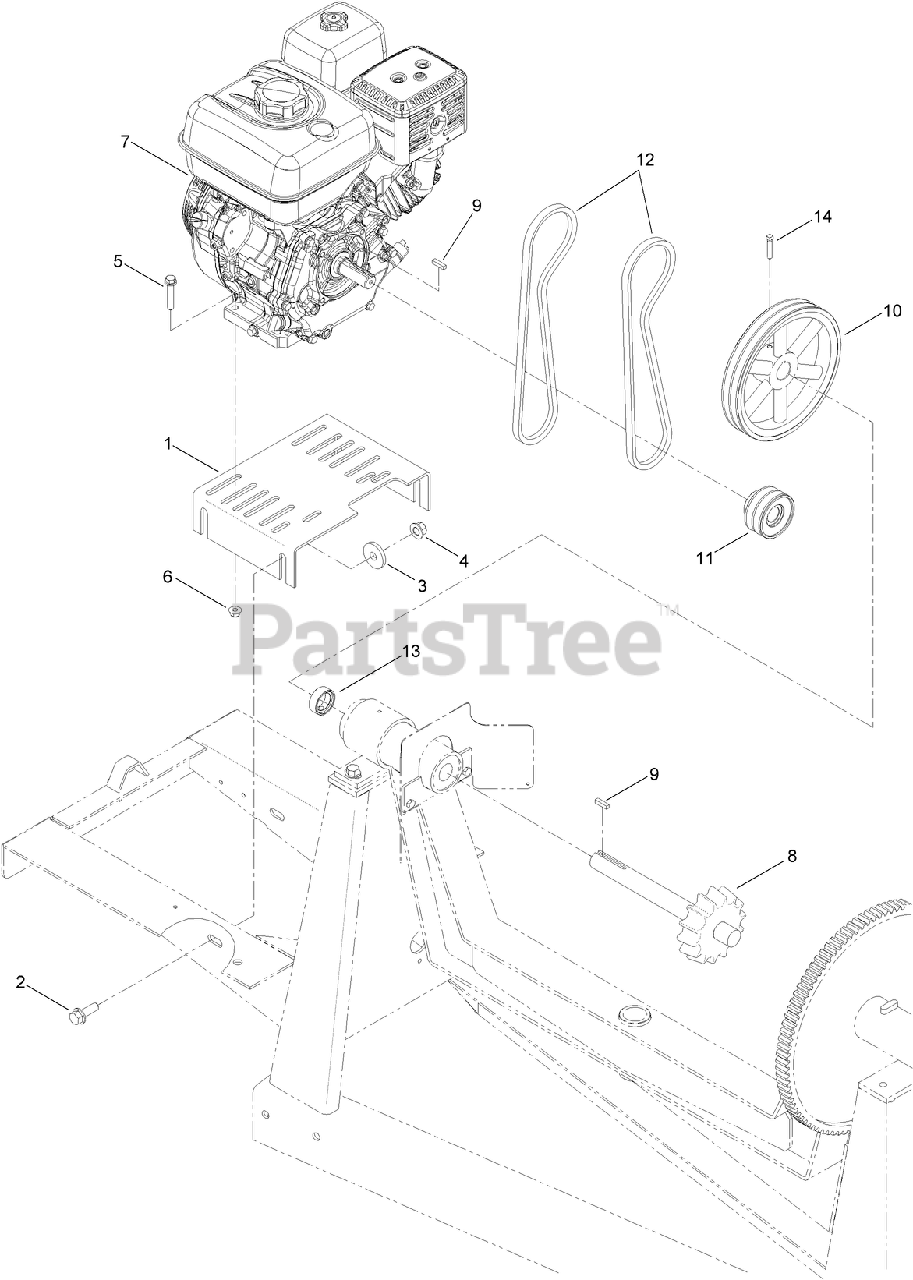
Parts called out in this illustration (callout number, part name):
1	BASE-MOTOR
2	SCREW-HHF
3	WASHER-FLAT
4	NUT-LOCK
5	SCREW-HHF
6	NUT-HF, NI
7	ENGINE-HONDA, GX240
8	SHAFT-DRIVE
11	SHEAVE
12	BELT-V
13	COLLAR-LOCKING
14	SCREW-SET
